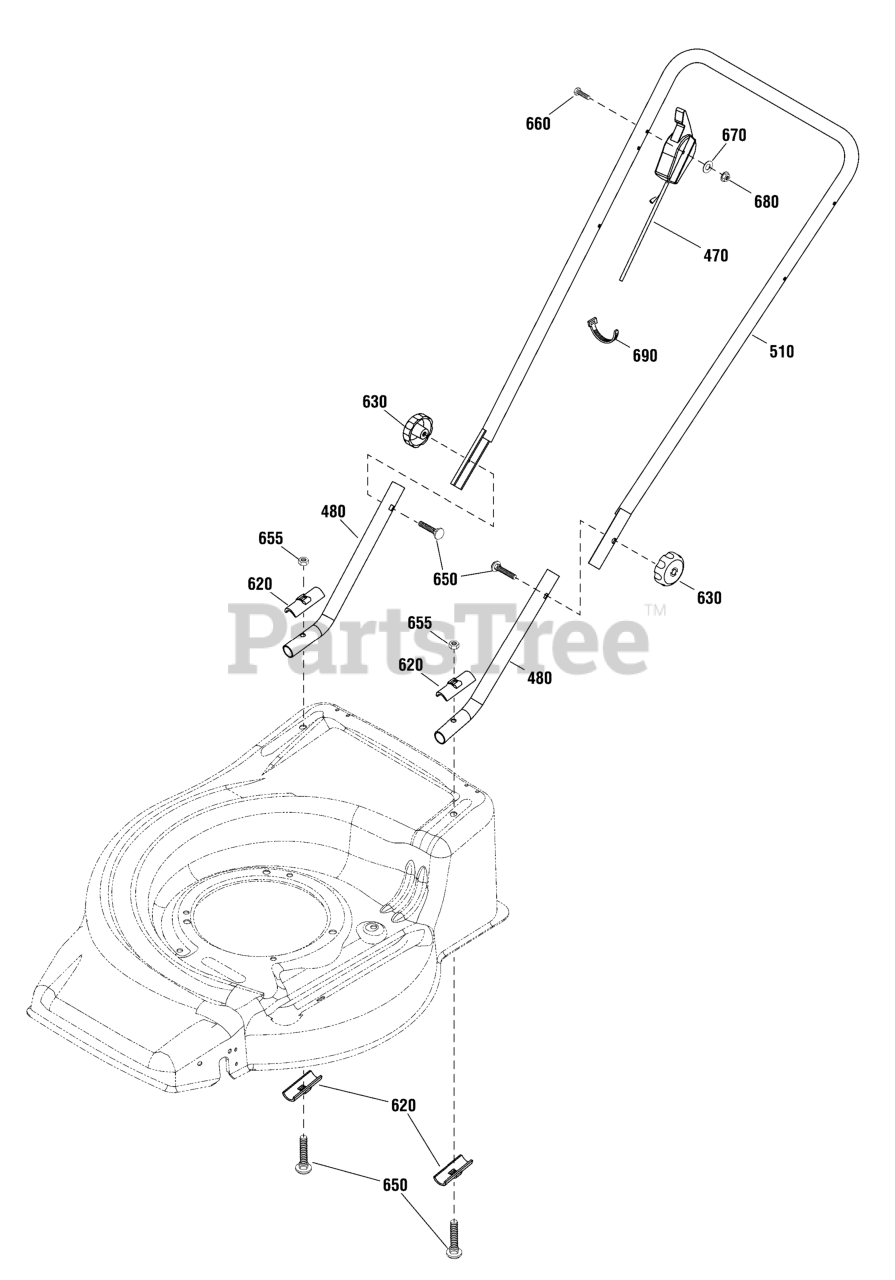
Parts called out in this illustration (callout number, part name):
470	THROTTLE CONTROL ASSEMBLY, 1180mm
480	HANDLE, Lower Classic
510	HANDLE, Upper, Straight
620	SADDLE PLATE
630	KNOB, Handle
650	BOLT, 5/16 x 1-3/4
655	NUT, Nylock, 5/16
660	SCREW, Pan Head Phillips, 10-24 x 1-3/4
670	WASHER, 3/16 ID x 5/8 OD
680	NUT, 10-24
690	* CABLE TIE
